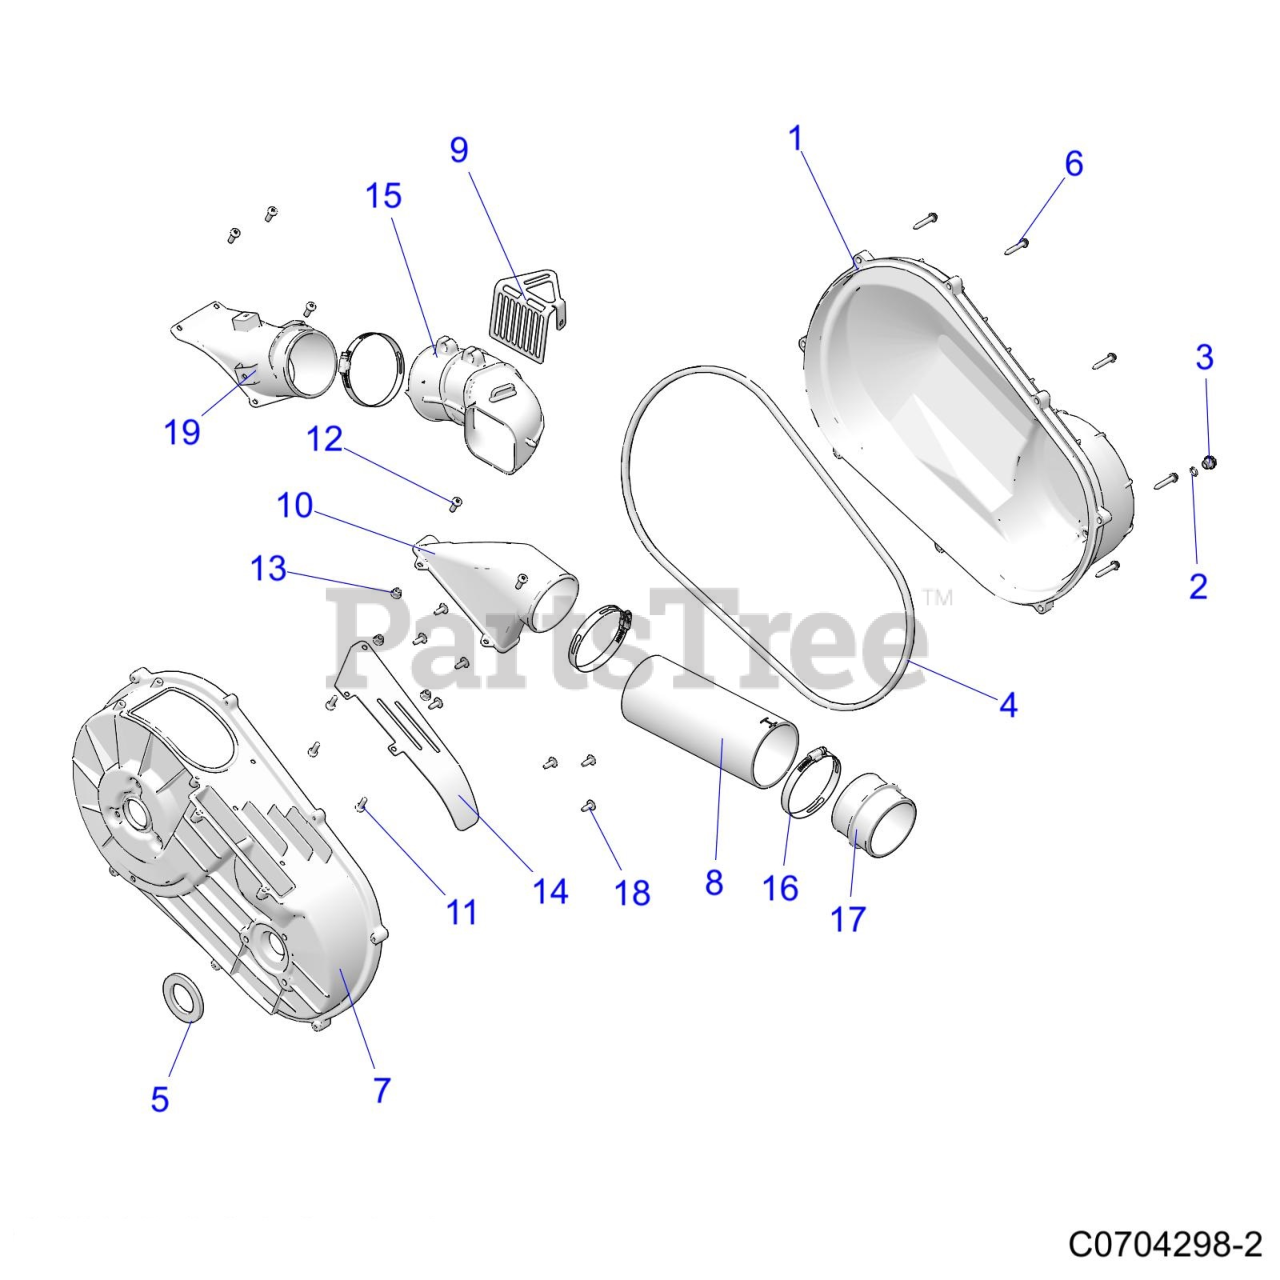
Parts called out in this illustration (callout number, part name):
1	K-CVR,CLUTCH,OTR,RGR XP
2	O RING-.364X.504X.07
3	PLUG-DRAIN
4	SEAL-OUTER CLUTCH COVER
5	SEAL, COVER, PTO
6	SCR-HXFL-M6X35 ZOD HILO
7	ASM., COVER, CLUTCH, INNER
8	HOSE-CLUTCH,INTAKE
9	BRKT-BELT SCREEN
10	DUCT-CLUTCH,AIR INLET
11	SCR-M6X1.0X20MM,TX,PH,8.8-B
12	SCR-#14X3/4 HI/LO-PH-PN TRX-M
13	NUT-HXFL-M6X1.0 8 ZB3 NYL
14	BRKT-GUARD,CLUTCH COVER
15	DUCT-CLUTCH,AIR OUTLET
16	CLAMP-HOSE SLOTTED,89-100 DIA
17	BOOT-HOSE ADAPTER
18	SCR-TXTH-M6X1.0X16 ZPB
19	DUCT-CLUTCH,AIR OUTLET
